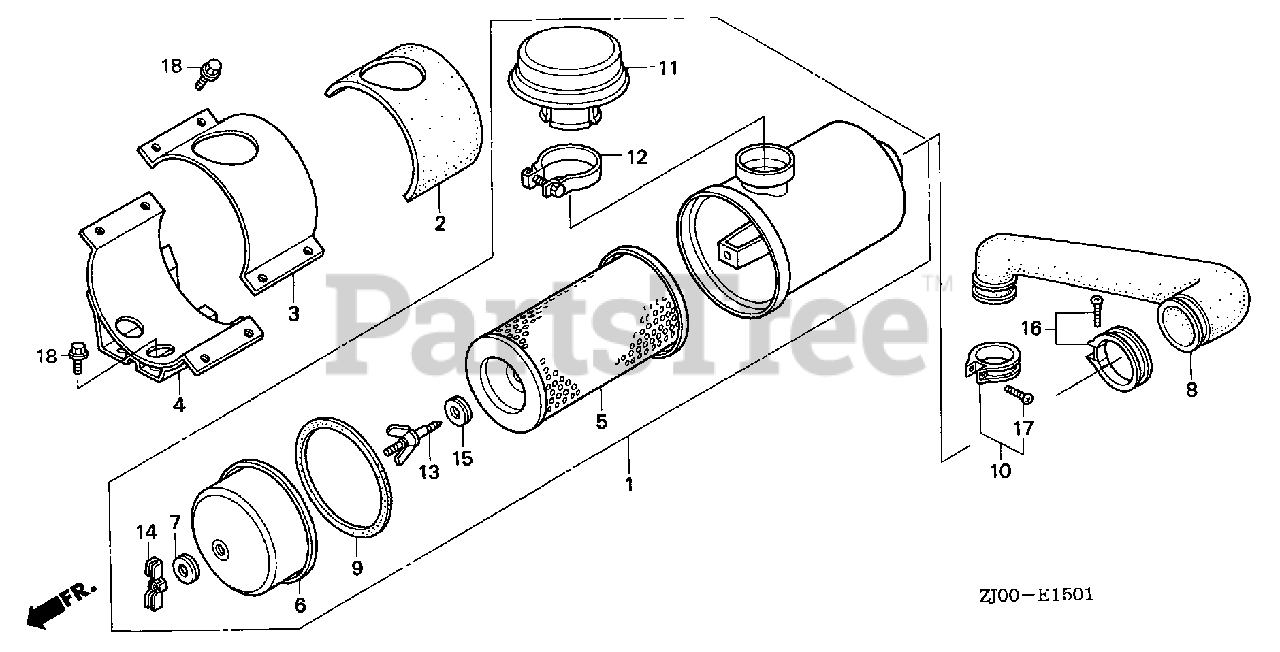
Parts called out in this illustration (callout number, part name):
1	AIR CLEANER ASSY. (NOT AVAILABLE)
2	RUBBER, AIR CLEANER HOLDER (UPPER)
3	HOLDER, AIR CLEANER (UPPER)
4	HOLDER, AIR CLEANER (LOWER)
5	ELEMENT, AIR CLEANER
6	COVER, AIR CLEANER
7	GROMMET, AIR CLEANER
8	TUBE, AIR CLEANER CONNECTING
9	SEAL, AIR CLEANER
10	BAND, AIR CLEANER CONNECTING TUBE
12	CLAMP ASSY.
13	BOLT, AIR CLEANER
14	WINGNUT (6MM) (BLACK)
15	WASHER, AIR CLEANER
16	BAND, AIR CLEANER CONNECTING TUBE (50)
17	SCREW, PAN (4X20)
18	BOLT, FLANGE (6X12)
